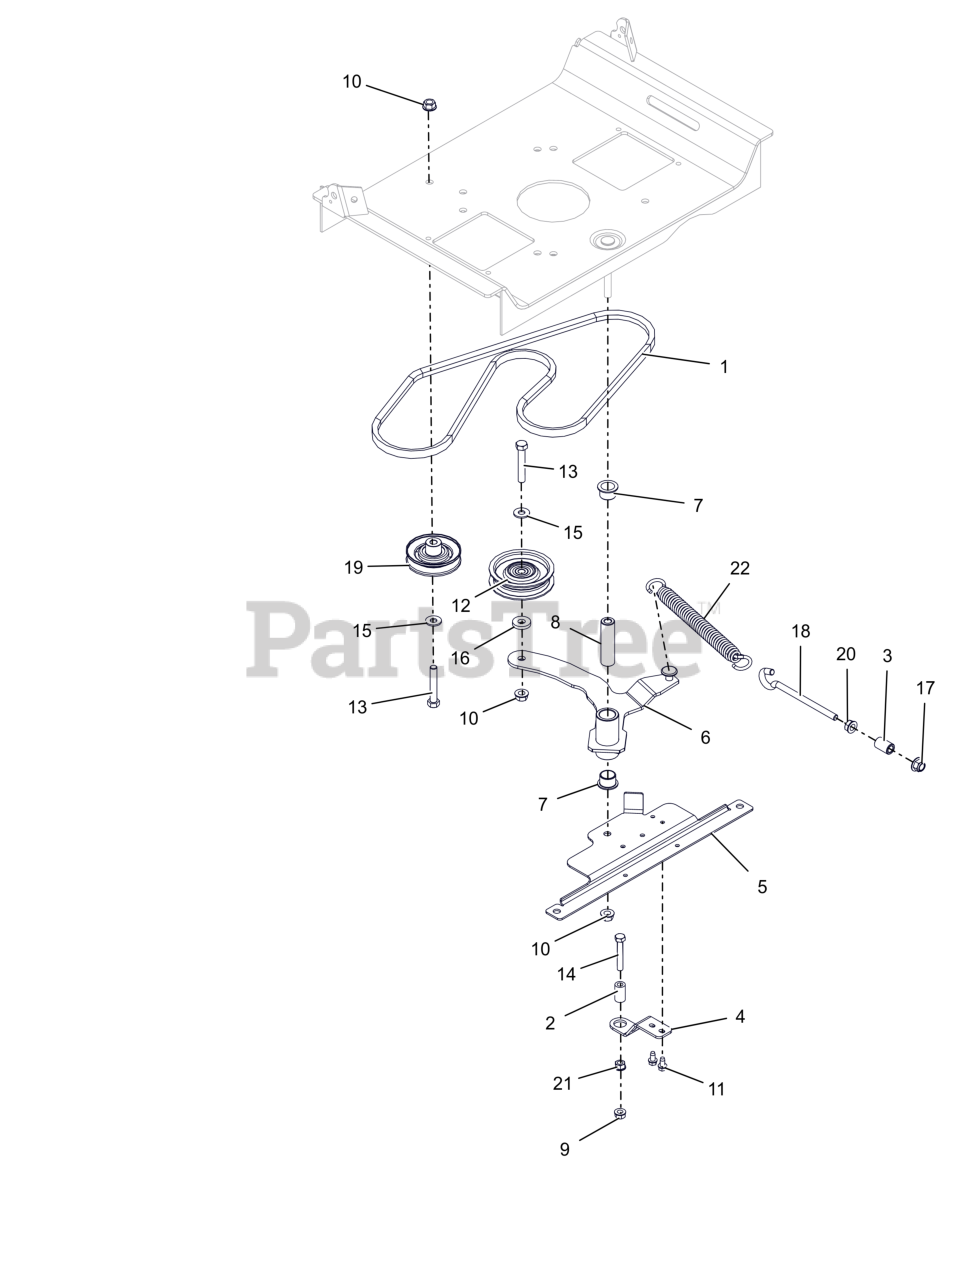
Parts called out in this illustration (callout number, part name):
1	V-BELT, A-RAW EDGE
2	SPACER, RUBBER 5/16 IDX1.0 LG
3	SPACER, .375X.625X.970 (PM)
4	BRKT, CLUTCH STOP (XL)
5	BRKT, IDLER ATTACHMENT (BLACK)
6	WLDMT,GRD DRIVE IDLER ARM-LGR
7	BSHG-FLG 0.75X0.875X.625X1.125
8	BUSHING, SLEEVE .38X.750X2.78
9	NUT-LK-TOP-FLG .312-18 GF ZCC
10	NUT-LK-TOP-FLG .38-16 ZC120
11	SCR-TAP .25-20X.50 HWH ZCC
12	SHEAVE, IDLER -V .38 x 4.00
13	BLT,HEX .38-16X2.25 G5 ZCC
14	BLT, HEX .31-18X2.00 G5 ZCC
15	WSHR,FLT .375X.875X.083 ZCC
16	WSHR, FLT .406X1.00X.188 ZCC
17	NUT,NYL-FLG .38-16 GF ZCC
18	BOLT,.38-16 X 4.25-.62 DIA EYE
19	IDLER, V-3.000 OD
20	NUT, SPNLK-FLG .38-16 G5 ZCC
21	NUT,SPNLK-FLG .31-18 G5 ZCC
22	SPRING, EXTENSION
